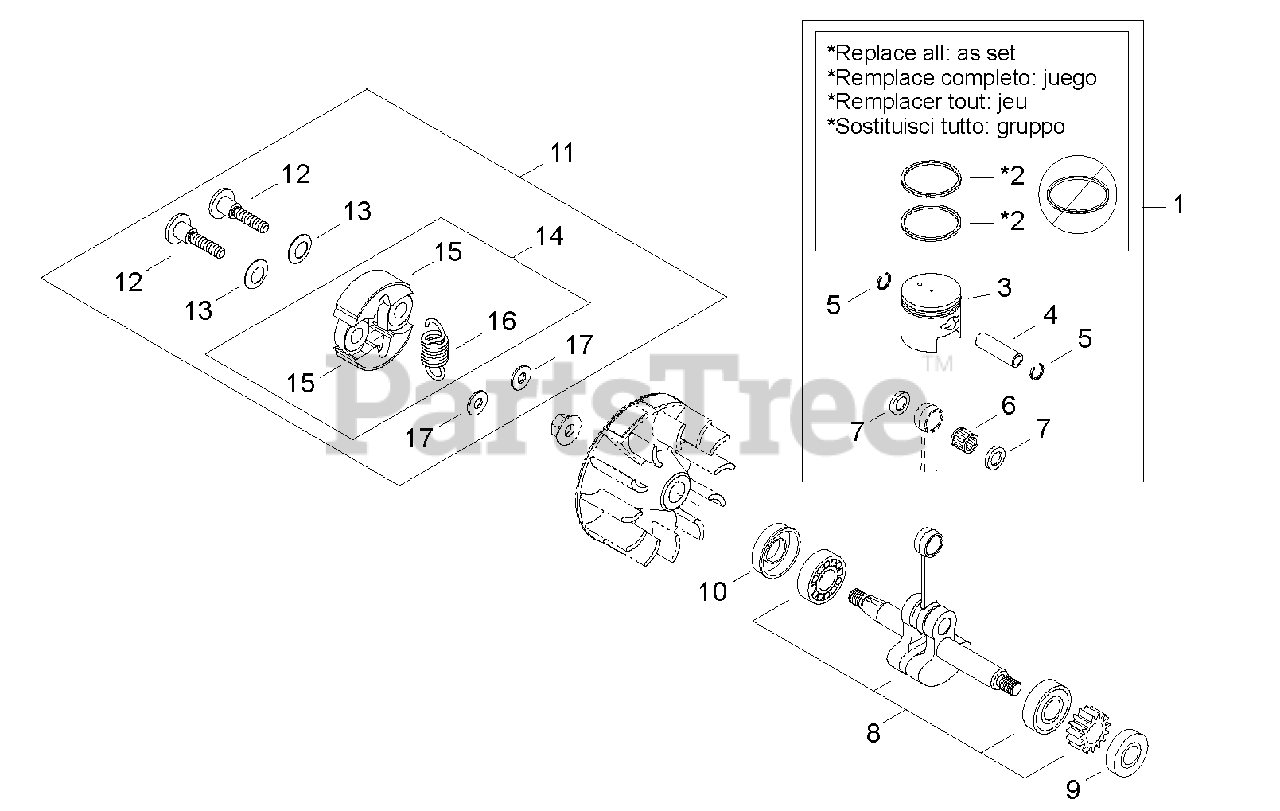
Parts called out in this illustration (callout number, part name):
1	PISTON KIT
2	RING, PISTON
3	PISTON
4	PIN, PISTON
5	RING, RETAINING
6	BEARING, NEEDLE
7	SPACER, PISTON
8	CRANKSHAFT ASSY
9	SEAL, OIL - 12
10	SEAL, OIL - 12
11	CLUTCH SHOE SET
12	BOLT, CLUTCH
13	WASHER - SPRING
14	CLUTCH ASSY
15	SHOE, CLUTCH
16	SPRING, CLUTCH
17	WASHER - 6
